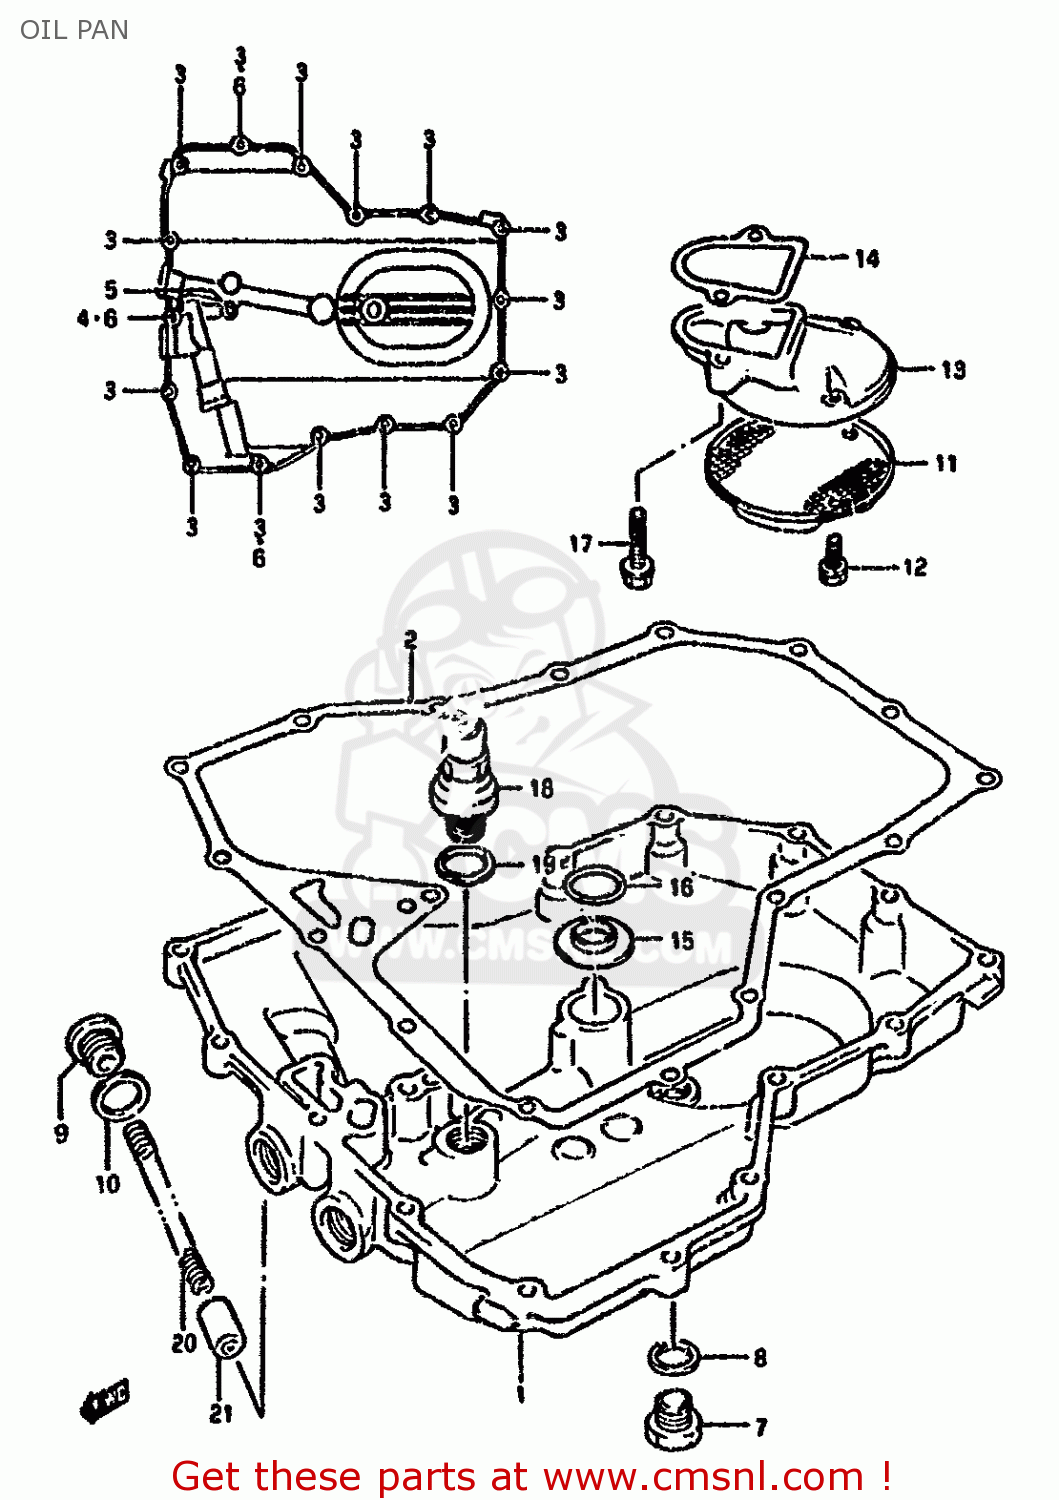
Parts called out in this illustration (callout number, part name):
1	PAN,OIL
2	GASKET,OIL PAN (NAS)
3	BOLT
4	BOLT
5	BOLT
6	GASKET(5.8X11X1.2) (NAS)
7	PLUG
8	GASKET(14X19.2X2) (NAS)
9	PLUG
10	GASKET(16X22X2) (NAS)
11	STRAINER,ENGINE OIL
12	BOLT
13	PROTECTOR,OIL STRAINER
14	GASKET,OIL STRAINER PROTECTOR (NAS)
15	GASKET,OIL OUTLET (NAS)
16	O RING(D:3.2,ID:17.8)
17	BOLT
18	VALVE ASSEMBLY,OIL RELIEF
19	GASKET(16X22X2) (NAS)
20	SPRING
21	PLUNGER,OIL CONTROLL
